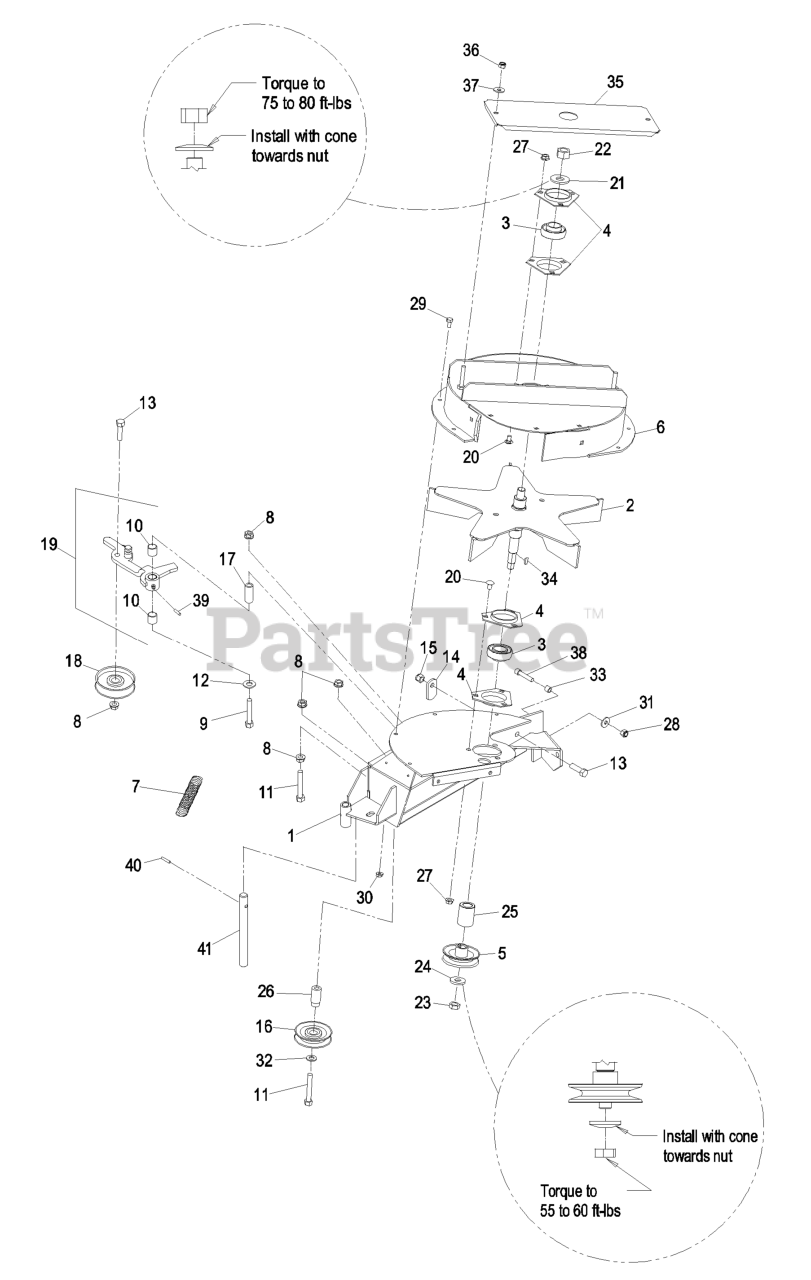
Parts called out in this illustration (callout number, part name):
1	WLD,BLOWER MOUNT
2	IMPELLER
3	BEARING
4	HOUSING-FLANGE
5	SHEAVE-BLOWER
6	ASM,UPPER HOUSING
7	SPRING-IDLER
8	NUT-HHF, WHIZ
9	SCREW-HSBH
10	BUSHING
11	BOLT-CARR
12	WASHER-FLAT
13	SCREW-HH
14	LATCH-CATCHER, GRASS
15	NUT-LOCK, NI
16	IDLER-INSIDE
17	BUSHING-PIVOT, IDLER
18	IDLER-FLAT
19	ASM, IDLER ARM - SERVICE
20	SCREW-CARR
21	WASHER-SPRING
22	NUT-HEX
23	NUT-JAM
24	WASHER-SPRING
28	NUT-HEX
29	SCREW-HH
31	WASHER-SPRING
32	WASHER-FLAT
33	BUSHING, LOCATOR
34	KEY-WOODRUFF
35	ASM, BEARING COVER
36	NUT-LOCK, NI
37	WASHER-FLAT
38	SCREW-HSH
39	FITTING-GREASE
40	PIN-ROLL
41	SHAFT-CATCHER, GRASS
